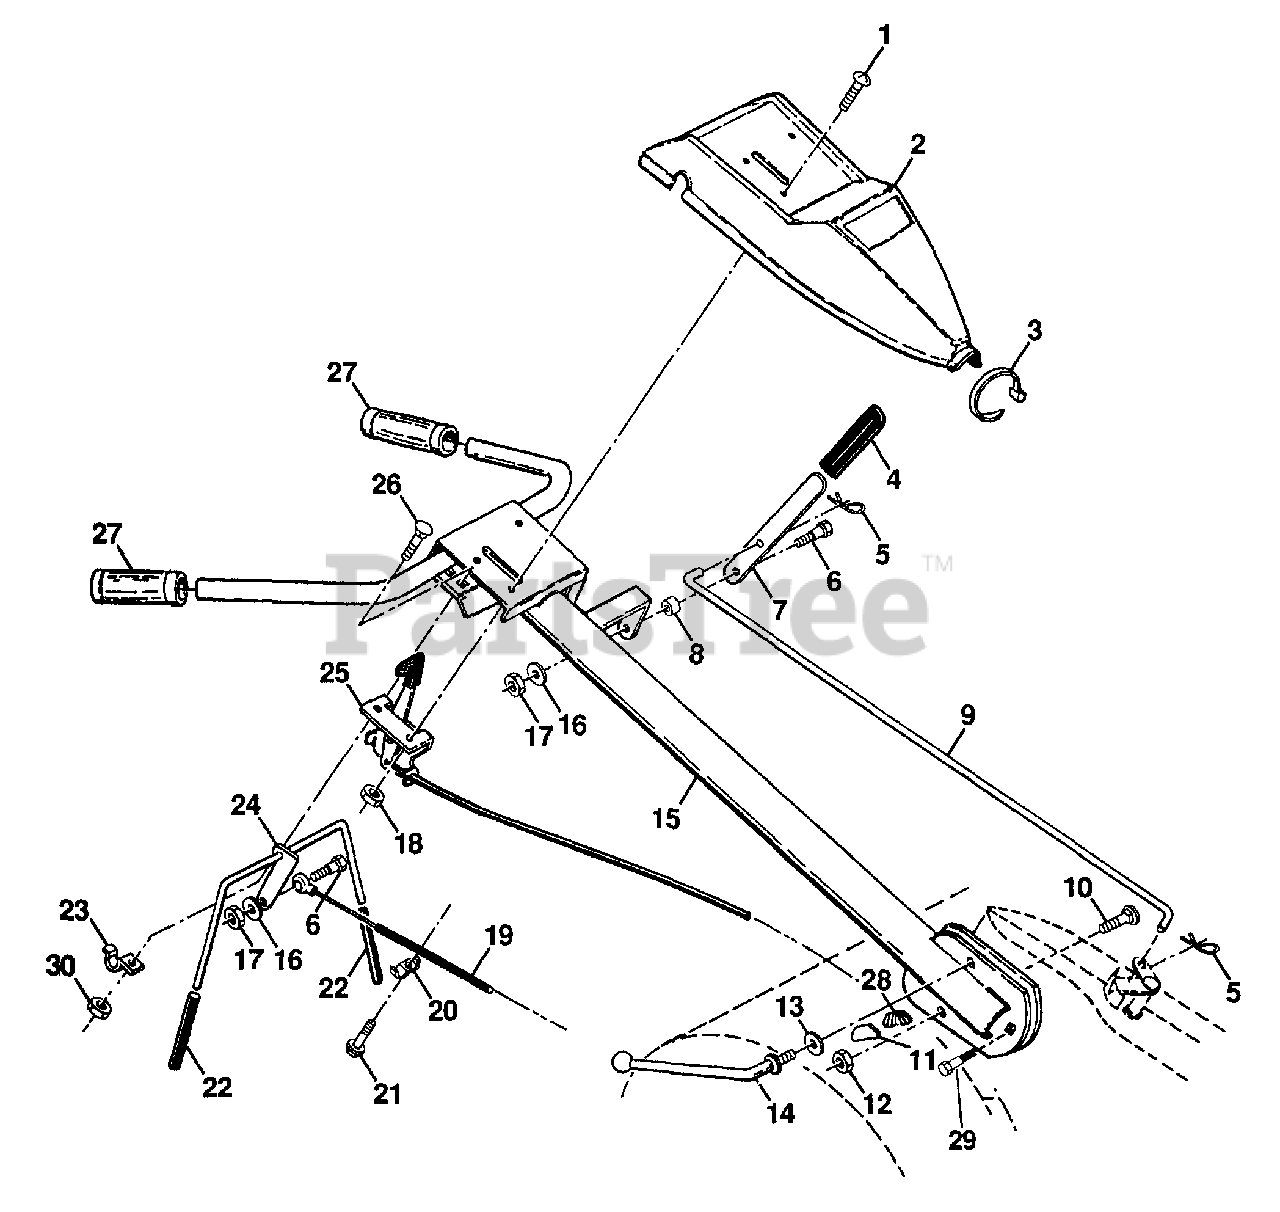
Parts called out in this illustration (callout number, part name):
1	Screw, Phd. #10-24
2	Panel, Control
3	Tie, Cable (AYP part number)
4	Grip, Handle (AYP part number)
5	Clip, Hairpin (AYP part number)
6	Bolt, Shoulder
7	Handle, Shift (AYP part number)
8	Grommet, Rubber (AYP part number)
9	Rod, Shift (AYP part number)
10	Bolt, Carriage 3/8-16 x 1 Gr. 5
11	Lock, Handle (AYP part number)
12	Nut, Centerlock 3/8-16
13	Washer 13/32 x 1 x 11 Ga.
14	Lever, Lock, Handle (AYP part number)
15	Handle
16	Washer, Lock 1/4
17	Nut, Hex 1/4-20
18	Nut, Keps #10-24 UNC
19	Cable, Clutch
20	Clip
21	Screw, Hex Washer Hd. Slotted #10-24 x 1/2 (AYP part number)
22	Grip, Bar, Control (AYP part number)
23	Clamp, Bar, Control (AYP part number)
24	Bar Assembly, Control (AYP part number)
25	Control, Throttle (AYP part number)
26	Bolt, Carriage 1/4-20 UNC x 1/2
27	Grip, Handle (AYP part number)
28	Nut, Keps 1/4-20
31	Bolt, Pivot
